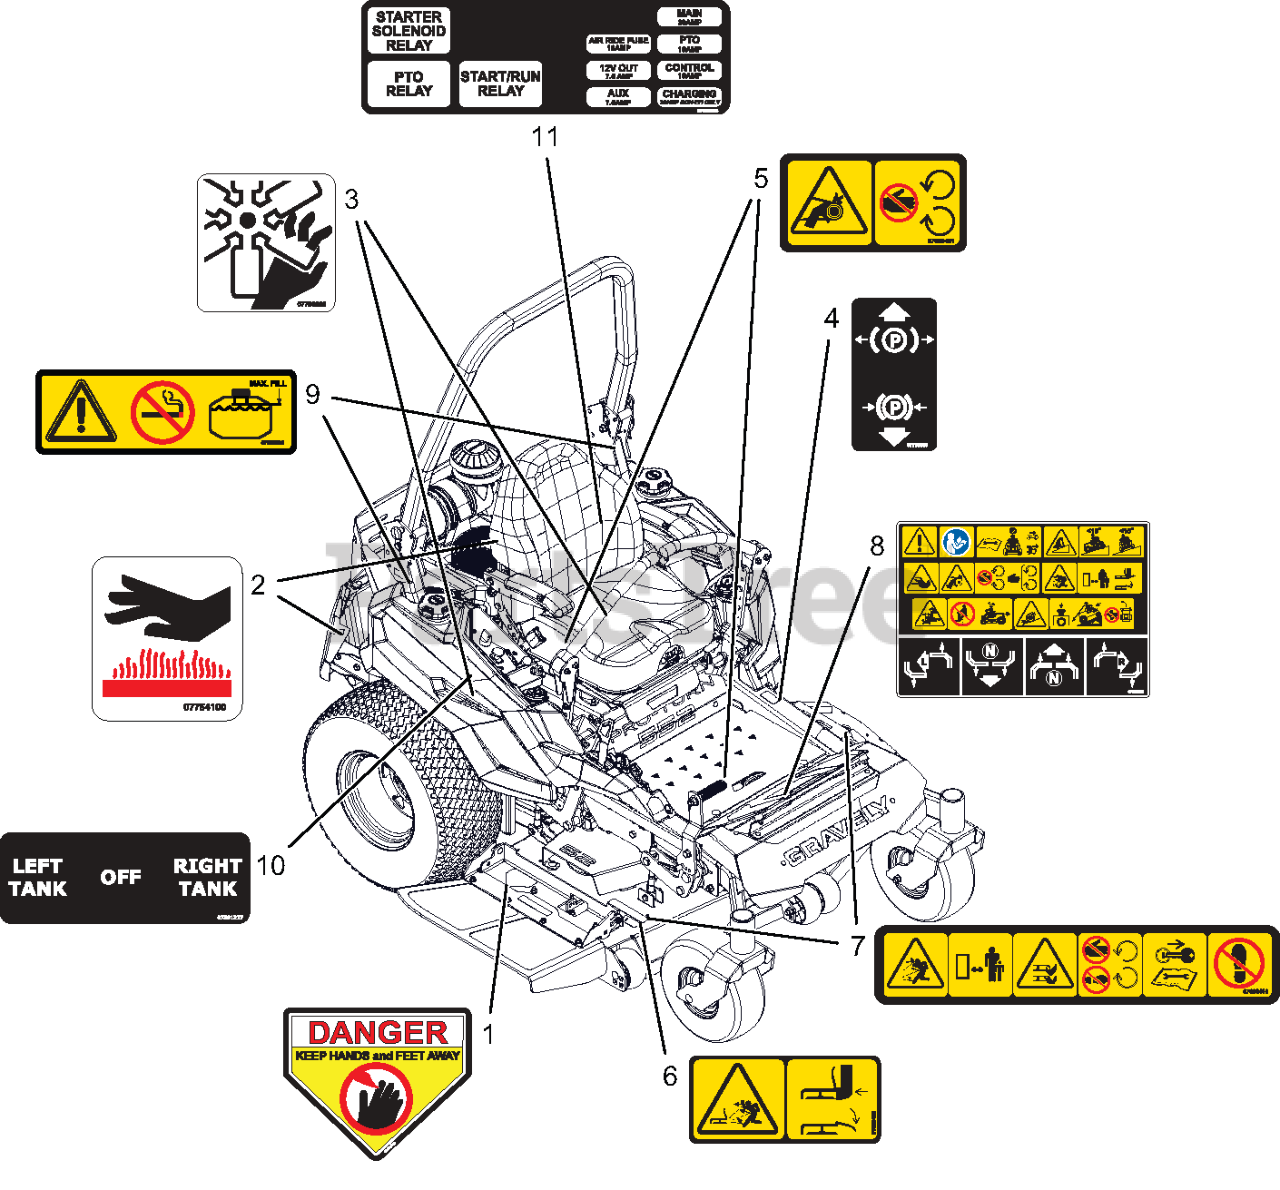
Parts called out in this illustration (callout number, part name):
1	DECAL, DANGER
2	DECAL, HOT SURFACE
3	DECAL, DANGER FAN
4	DECAL, PARKING BRAKE LEVER
5	DECAL, SAFETY - GUARDING
6	DECAL, SAFETY - DECK GUARDING
7	DECAL, DECK SAFETY
8	DECAL, INSTR SAFETY
9	DECAL, FUEL WARNING
10	DECAL, FUEL VALVE
11	DECAL, FUSE BLOCK PT300/500
